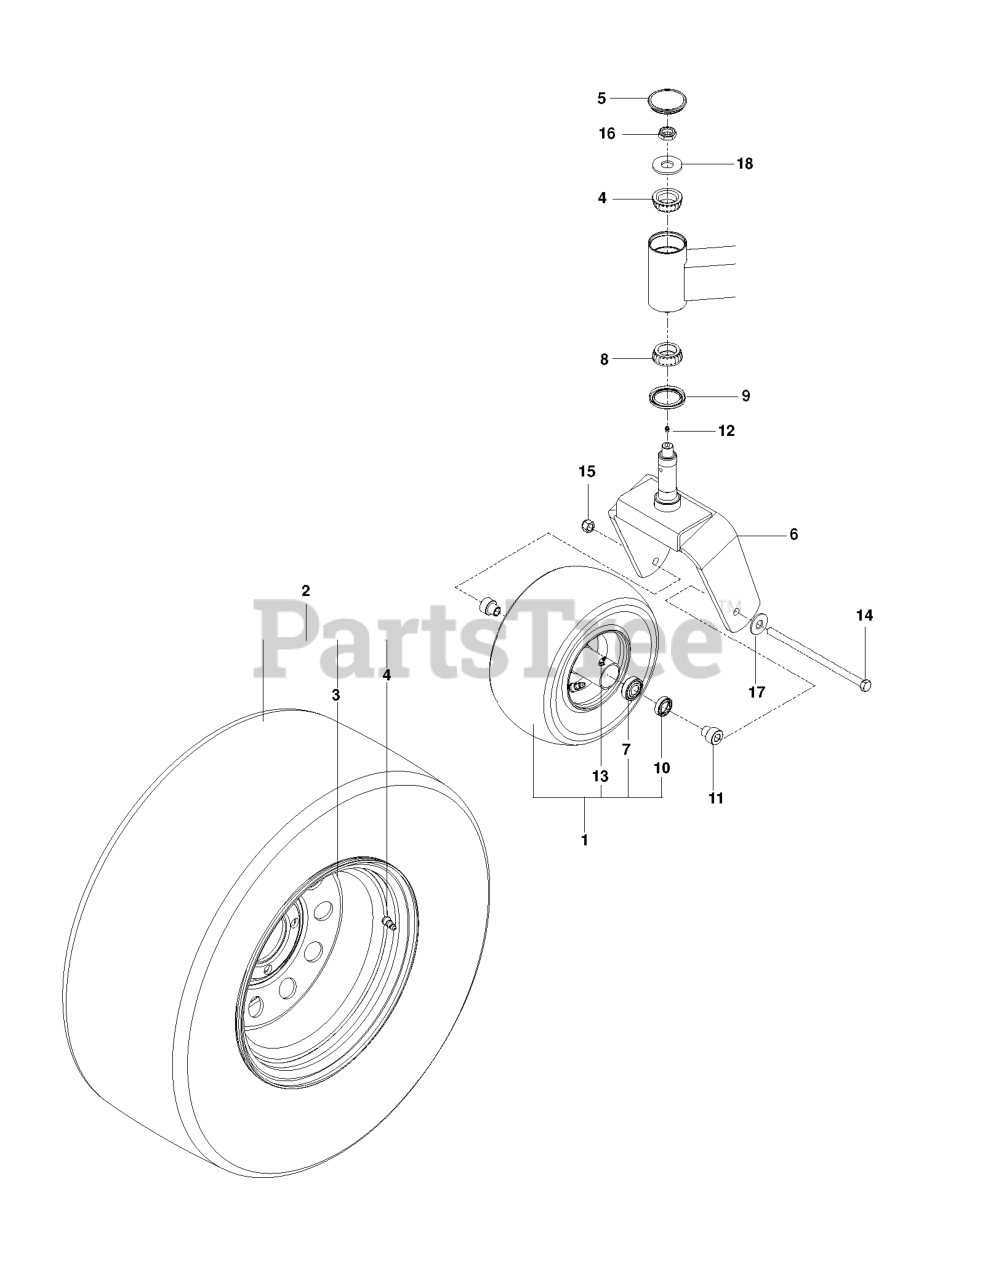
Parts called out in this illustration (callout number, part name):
1	TIRE, 13 X 6.5-6 NO FLAT
2	WHEEL/TIRE.ASM.24X12-12.SILVER
3	12"RIM 2.5" NEG OFFSET 8.5" W
4	VALVE STEM TR-412
6	FORK.CASTER.ORANGE
7	TAPERED BEARING W/RACE
8	BEARING W/CUP TAPPER ROLLER
9	SEAL, BEARING
11	AXLE SPACER
13	ZERK
14	HEX SCREW 1/2-13 X 9.5 GR5
15	NUT, 1/2-13 HEX FLG NYLOC ZD
16	NUT, 3/4-16 HEX THIN NYLOC ZD
17	WASHER 1/2" FLAT
18	WASHER, 3/4 HARDENED
